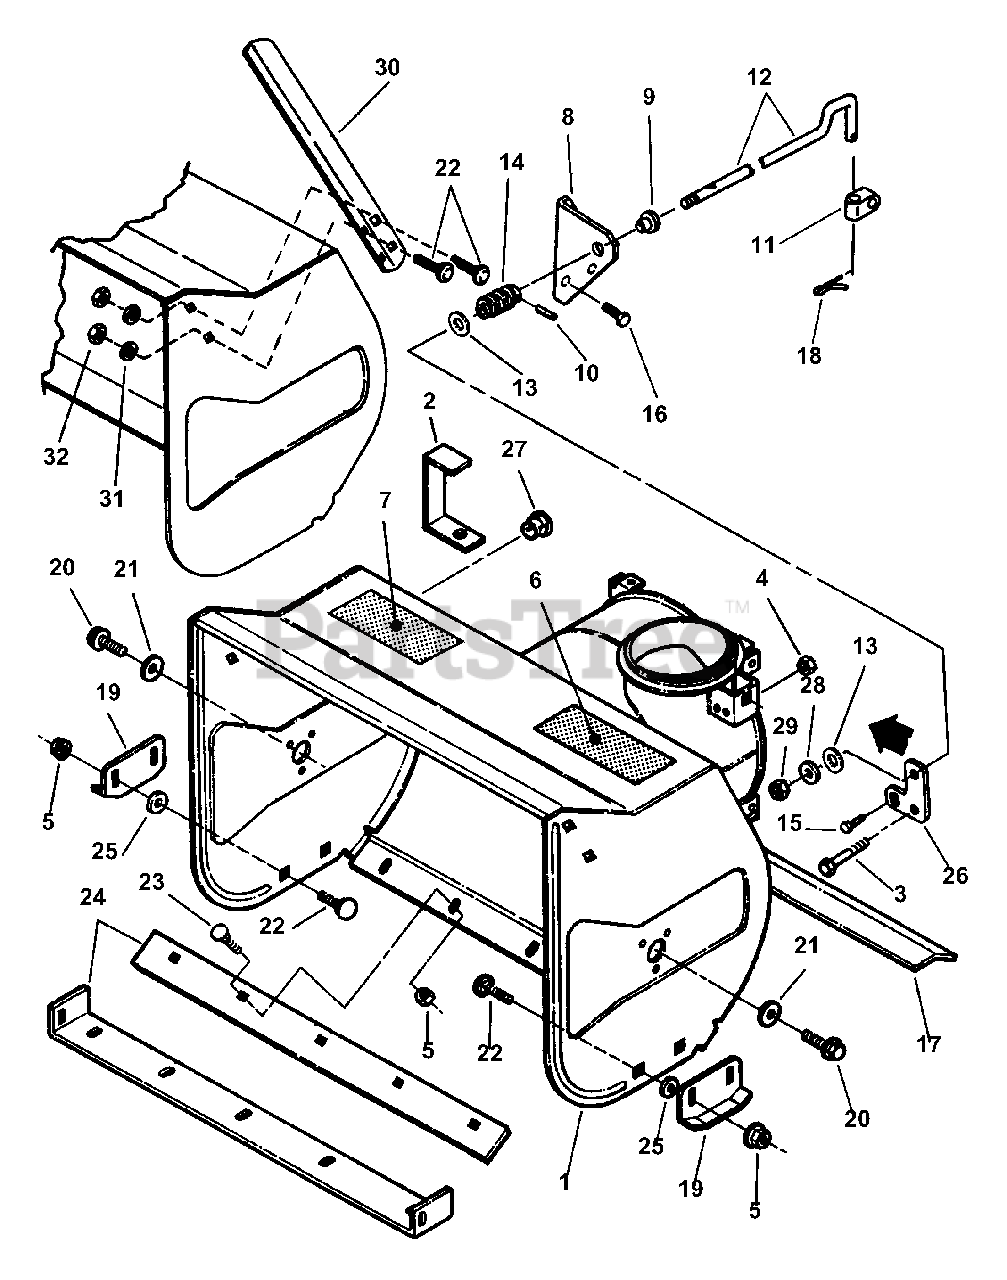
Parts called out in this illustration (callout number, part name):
1	ASSEMBLY, 24" Blower
2	GUIDE, Cable
3	SCREW, 5/16-24 x 3/4" Hex Head Cap, Grade 5
4	NUT, 5/16-24 Hex Center Lock, Grade B
5	NUT, 5/16-18 Hex Flange Lock, Grade 5
6	DECAL, Danger Rotating Auger
7	DECAL, Heavy Duty Snow
8	BRACKET, Worm Shaft Support
9	BUSHING
10	PIN, 1/8 x 3/4" Roll
11	CONNECTOR
12	SHAFT, Worm (3/8-16 threaded)
13	WASHER, 13/32 Spring
14	WORM
15	SCREW, 1/4-20 x 1/2" Hex Washer Self-Tap
16	SCREW, 5/16-18 x 1/2" Hex Washer Self-Tap
17	BAR, Stiffener
18	PIN, 3/32 x 3/4" Cotter
19	SHOE, Skid
20	SCREW, 3/8-16 x 1" Hex Washer Self-Tap
21	WASHER, 3/8" Flat
22	BOLT, 5/16-18 x 3/4" Short Neck Carriage, Grade 5
23	BOLT, 5/16-18 x 1/2" Short Neck Carriage, Grade 5
24	BLADE, Scraper
25	WASHER, 5/16 Flat
26	BRACKET, Worm
27	PLUG, 5/16" Dome
28	WASHER, 3/8" Flat
29	NUT, 3/8-16 Hex Center Lock, Grade 5 or B
30	DRIFT CUTTER
31	WASHER, 5/16 Split Lock
32	NUT, 5/16-18 Hex
